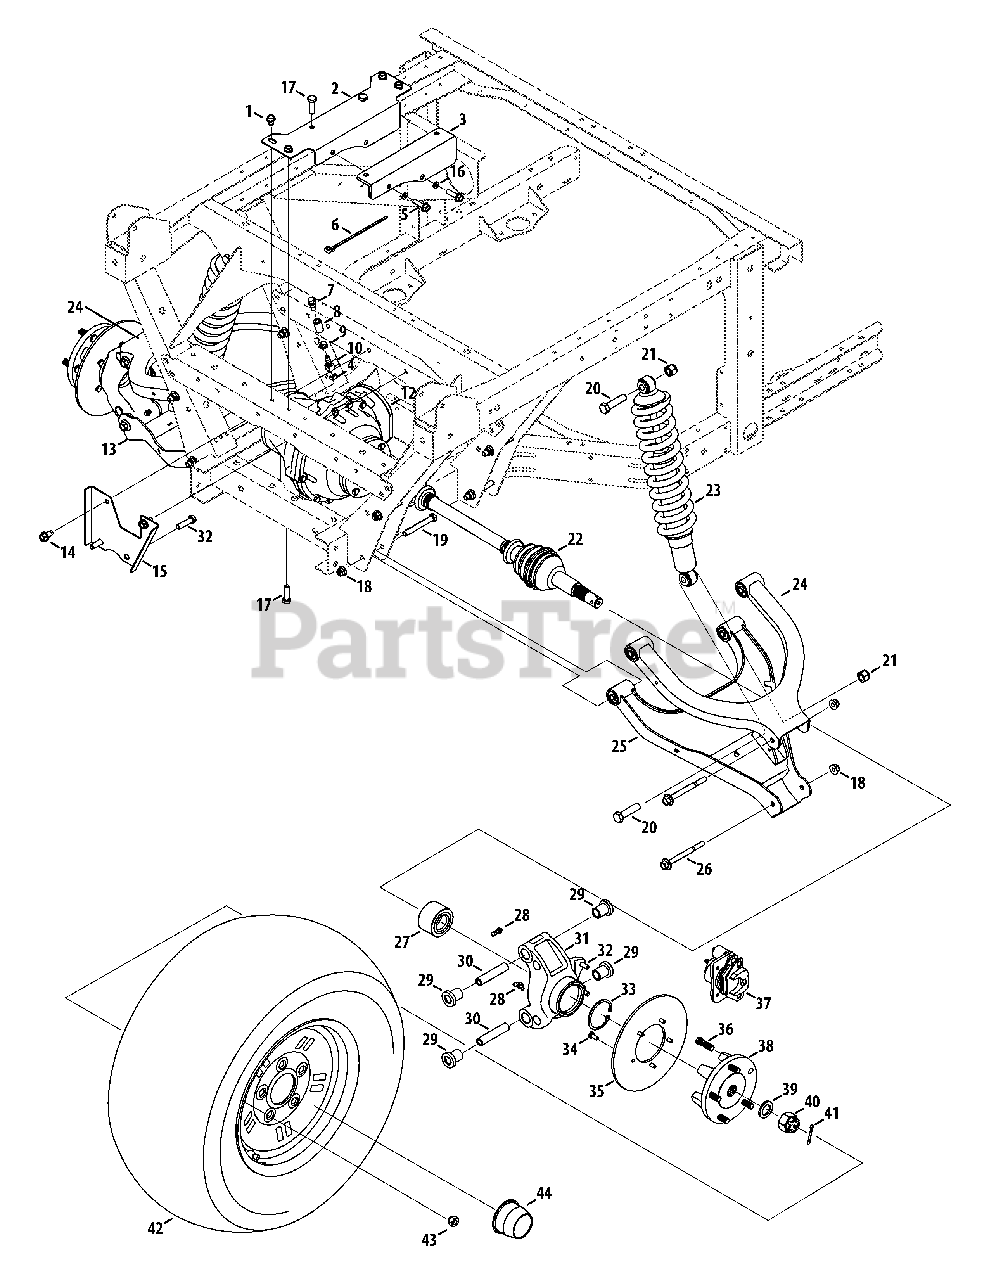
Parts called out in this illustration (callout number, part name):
1	Screw, tt, 5/16-18 x 0.500
2	Bracket, rear/diff, 4x4
3	Spacer, Differential
4	Nut, Jam, M12 x 1.5 x 6MM
5	Screw, 3/8-16 x 2.25, gr5, std
6	Tie, Cable
7	Vent, 3/8 Dia.
8	Hose, fuel Line
9	Clamp, hose, .490 Dia.
10	Fitting, Fuel Pickup
11	Washer, Flat, .344 x .688 x .065
12	Differential Assembly, complete
13	Control Assembly, lwr, l/rr
14	Screw, tt, 3/8-16 x .750
15	Bracket, Diff, rr
16	Washer, Flat, .385 x .870 x .092
17	Screw, 3/8-16 x .875, gr5, std
18	Nut, Flange Lock, 3/8-16, Nylon
19	Screw, 3/8-16 x 3.00, gr8, std
20	Screw, 1/2-13 x 2.00, gr5, std
21	Nut, Hex Lock, 1/2-13, Nylon
22	Axle Assembly, cv Joint
22	DOJ Boot Kit (Incl. clamp)
22	Rzeppa Boot Kit (Incl. clamp)
23	Shabs, 5.0 Stroke, rr
24	Control Assembly, rr Upr
25	Control Assembly, lwr, r/rr
26	Screw, 3/8-16 x 4.00, gr5
27	Bearing, dble Row, 60x30x37
28	Fitting, Grease
29	Bearing, Flange, .625 x .750 x .750
30	Tube, pivot, rr/cont Arm
31	Housing, rr, mach
32	Screw, m8-1.25, 25.00
33	Ring, retainer, dho-60
34	Screw, 1/4-20 x .625, gr5, lock
35	Disc, brake, 8.00x.188
36	Stud, rib Neck, 7/16-14 x 1.6
37	Brake, hydraulic, caliper, RH
38	Hub, wheel
39	Washer, flat, .88 x 1.38 x .125, ht
40	Nut, slotted, 22x1.5
41	Pin, cotter, 5/32, 1.25
42	Wheel Assmbly, RH,25 x 11-12
42	Wheel Assmbly, LH, 25 x 11-12, blk
42	Tire Only, 25x11-12
42	Wheel Assmbly, RH 26 x 11-12
42	Wheel Assmbly, LH, 26 x 11-12
42	Tire Only, 26x11-12
42	Wheel Assembly, 25x10-12
42	Tire Only, 25x10.5-12
43	Nut, lug, 7/16-14
43	Nut, lug, 7/16-14, Chrome
44	Cap, Wheel UV
44	Cap, Wheel UV, Chrome
